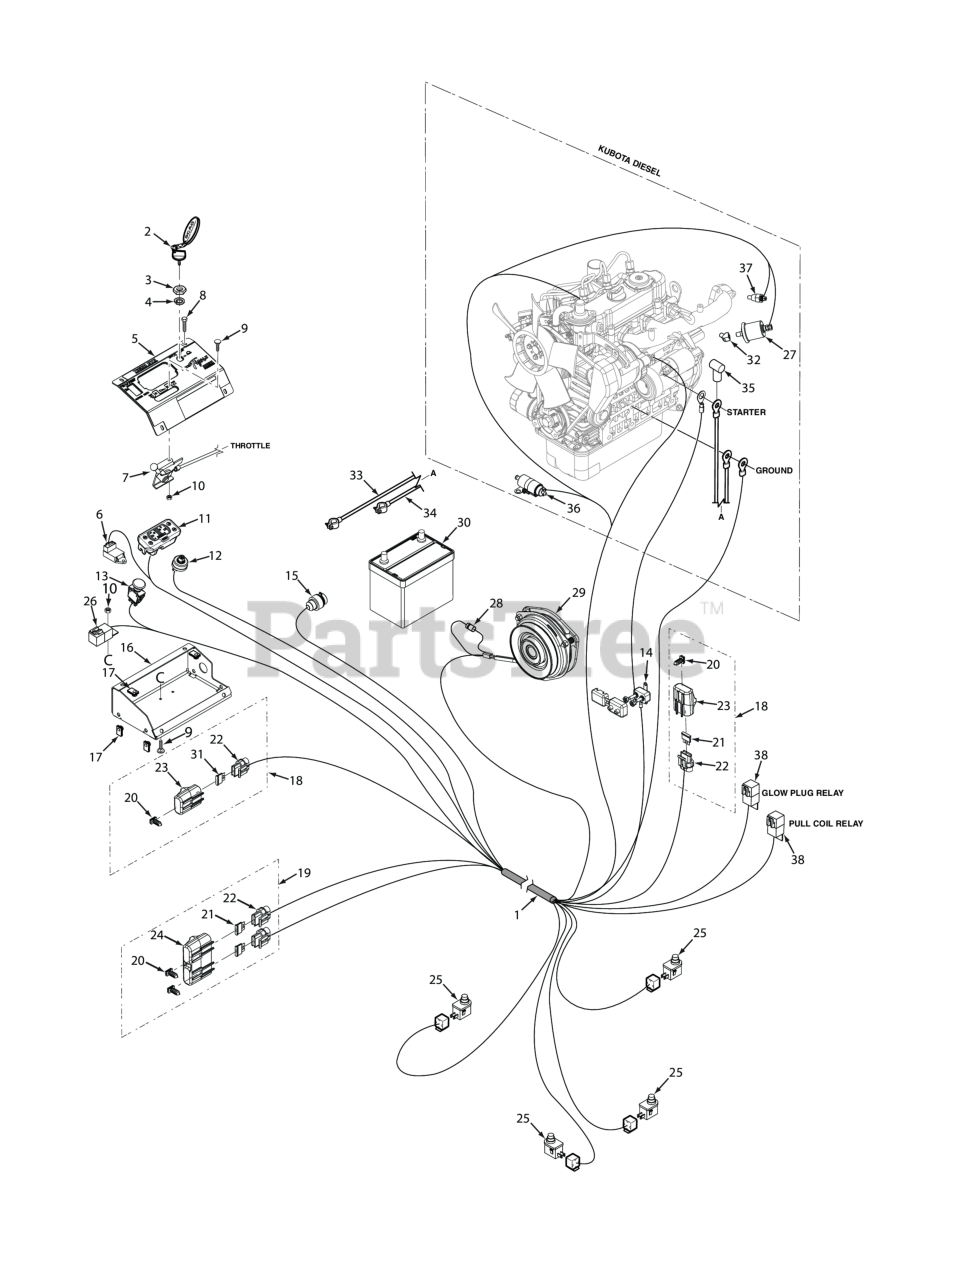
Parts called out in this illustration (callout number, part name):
1	Wire Harness, STTII-25KBD
2	Key, Assembly w/Fob
3	Nut, 5/8-32 Special
4	LOCK WASHER, 5/8" INTERNAL TOOTH
5	Instrument Panel w/Decal
6	Timer, Glow Plug
7	Cable, Control (Throttle)
8	Bolt, Hex Head Serrated Flange 1/4-20 x 3/4"
9	Bolt, Carriage #10-24 x 1/2"
10	Nut, Elastic Stop #10-24
11	Tiger Eye, Cluster Gauge
12	KEY SWITCH(INCLUDES MOUNTING HARDWARE)
13	Switch, PTO - 10 Amp
14	50 Amp Breaker
15	Power Plug, 12V
16	Base, Instrument Panel
17	Bolt, Hex Head 3/8-16 x 1"
18	Single Fuse Assy., Excluding Fuse
19	Double Fuse Assy.
20	Clip, Fuse Holder
21	FUSE, 20 AMP BLADE TYPE AUTOMOTIVE
22	Fuse Holder Assembly
23	Cover, Sealed Single
24	Cover, Sealed Double
25	Switch, Interlock, Normally Open
26	Relay, 12V 40 AMP Standard
27	Sender Unit, Oil Pressure
28	Diode, 600V 6 Amp
29	Clutch Assembly, GT3.5 (Diesel Engine)
30	Battery, 525 CCA
31	Fuse, 5 Amp
32	Elbow, 45 Degree Street
33	Battery Cable, 14" Red w/Braid
34	Battery Cable, 21" Black
35	Boot, Positive Battery Terminal
36	Solenoid, Fuel Shut-Off
37	Temperature Sensor, Engine Coolant
38	Relay, 12V 40 AMP Hi Capacity
